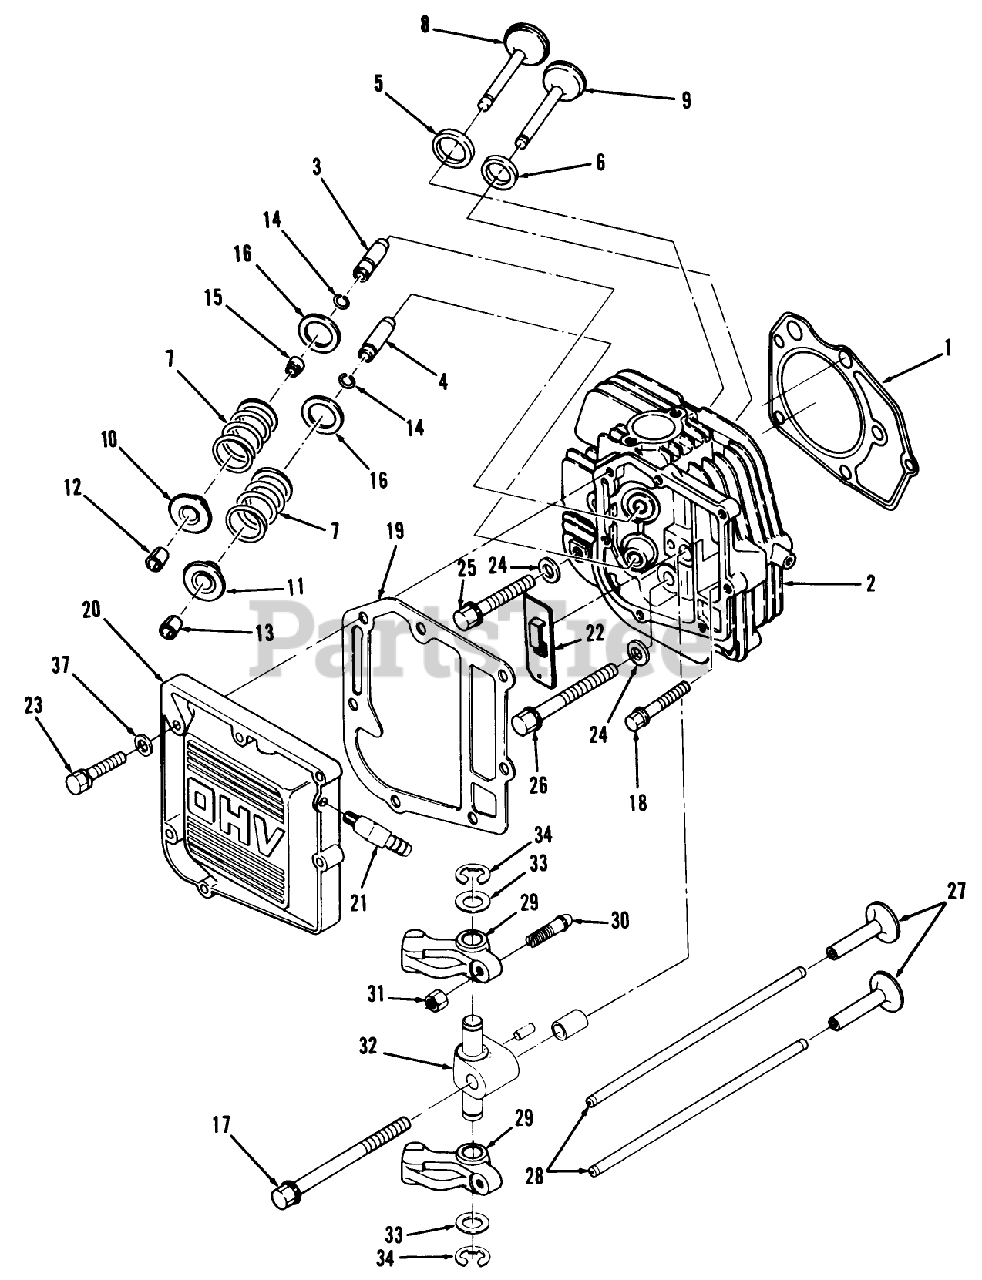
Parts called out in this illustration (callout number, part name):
1	GSKT-CYL HEAD
4	GUIDE-EXH VALVE
5	Seat-Intake Valve
6	Seat-Exhaust Valve
23	SCRW-CP SH M6X25MM
37	WASHER-FLAT
